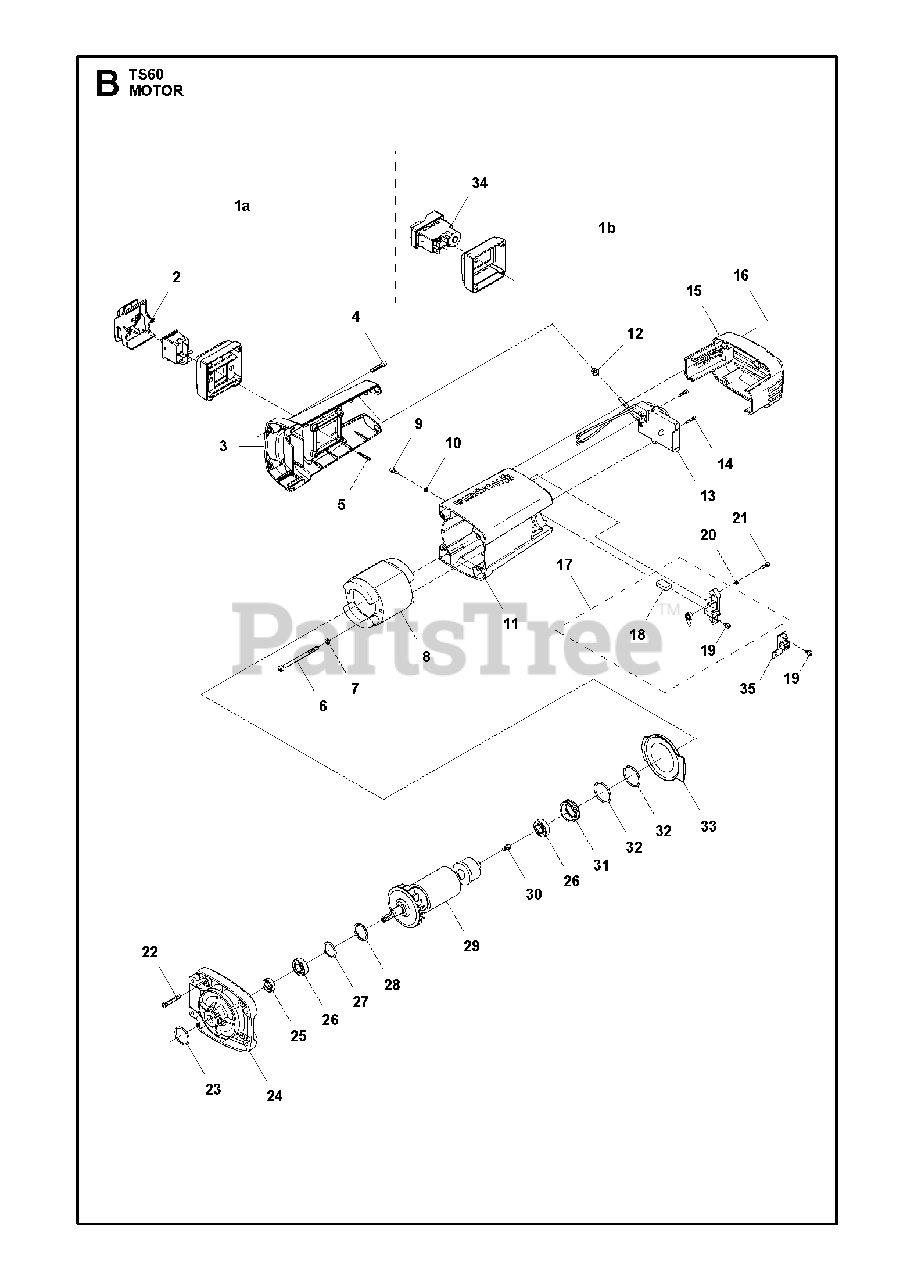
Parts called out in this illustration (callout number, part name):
6	SCREW IHSCM
11	MOTOR HOUSINGOnly for Canada
17	BRUSH HOLDERContains two brushes and two springs
18	BRUSH KITContains two brushes and two springs
20	SPRING WASHER
27	SPRING WASHER
31	BEARING SUPPORT
